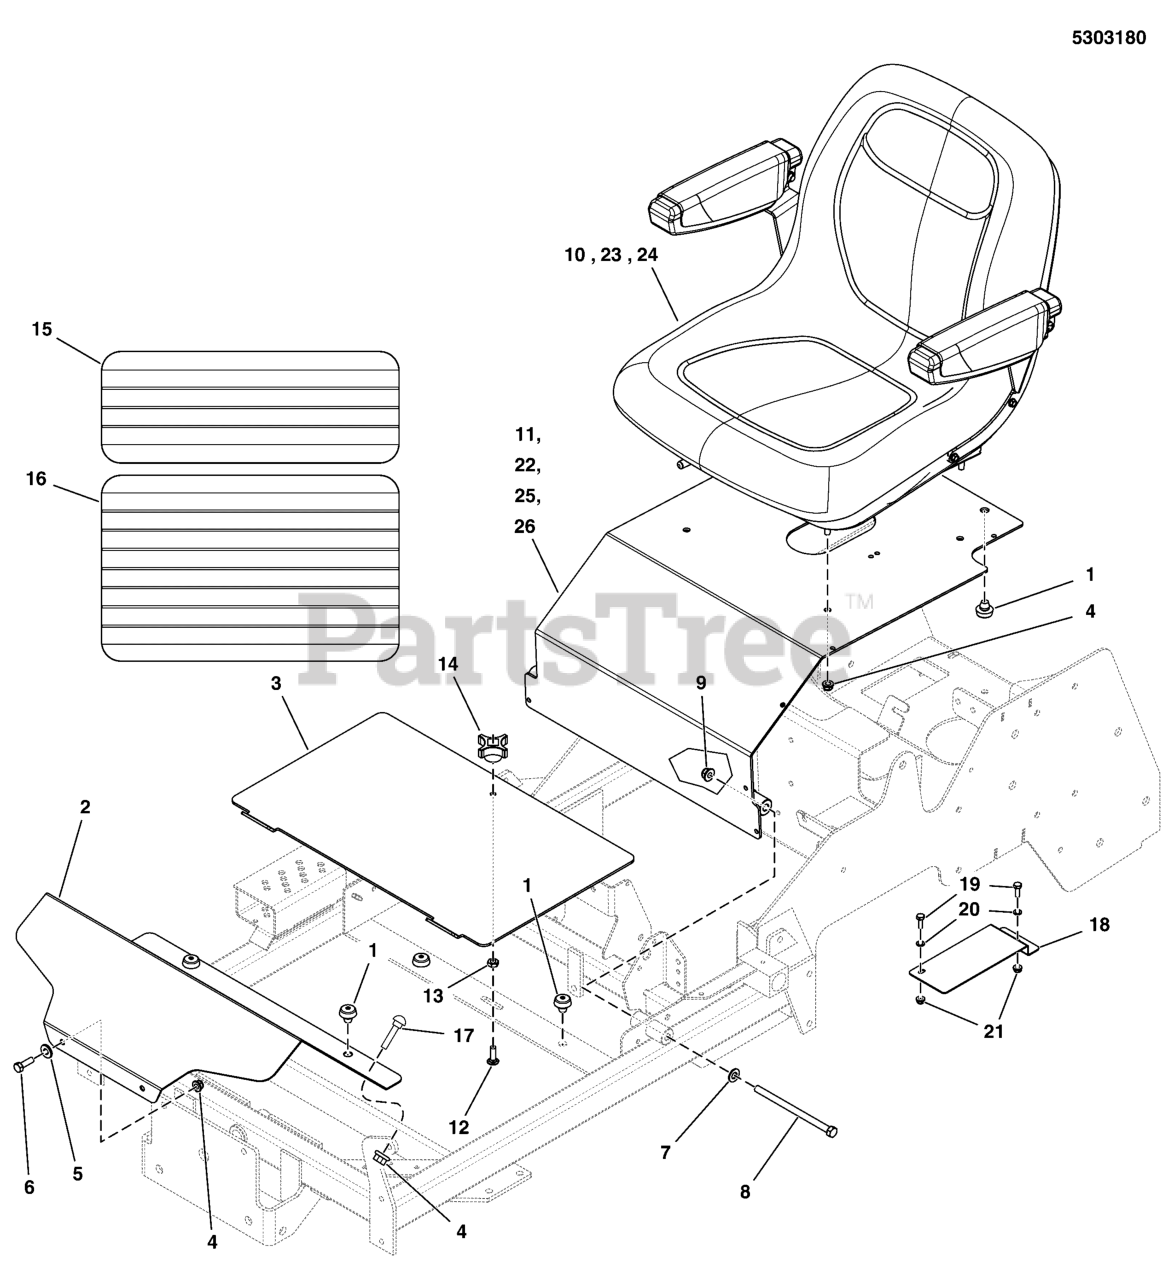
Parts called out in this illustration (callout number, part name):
1	MNT, VBRTN, RBBR
2	PLATE, FLOOR, RIDGID, IS700 - RED
3	PLATE, FLOOR, REMOVABLE, IS700 - RED
4	NUT, 5/16-18 HEX NYLOCK FLANGE
5	WASHER, 5/16" SAE
6	BOLT, 5/16-18 X 1 GD5 YZ
7	WASHER, 3/8 SAE
8	BOLT, 3/8-16 X 5-1/2" GD5 CZ
9	NUT, 3/8-16 HEX NYLOCK FLANGE
10	SEAT, XB-180, NO LOGO, BLACK
11	ASSM, SEAT PLATE W/DECALS - IS700Z (5409985B)
12	BOLT, 5/16-18 X 1-1/4, CARRIAGE YZ
13	NUT, 5/16-18,GR8, HEX, CNTR LK, ZINC/CL
14	KNOB-INT THR .312-18 4-ARM 2.12WD 1.06LG
15	SAFETY WALK, FLOOR REST, 6.00 X 16.00
16	SAFETY WALK, FLOOR PLATE, S50X, 10X16
17	BOLT, 5/16-18 X 3/4, CARRIAGE
18	PLATE, SEAT BELT GUARD, IS700 - BLK
19	SCREW, 1/4-20 X 1, ALLEN BH, CZ
20	WASHER, 1/4 SAE
21	NUT, 1/4-20, NYLOCK FLANGE
22	ASSM, SEAT PLATE W/DECALS - IS700Z, ANSI-EXP (5409985B)
23	SEAT, 907 SEAT INC
24	SEAT, 907 WITH ARM RESTS W/ SWITCH
25	ASSM, SEAT PLATE W/DECAL (5416034B)
26	ASSM, SEAT PLATE W/DECALS, EXP (5416034B)
